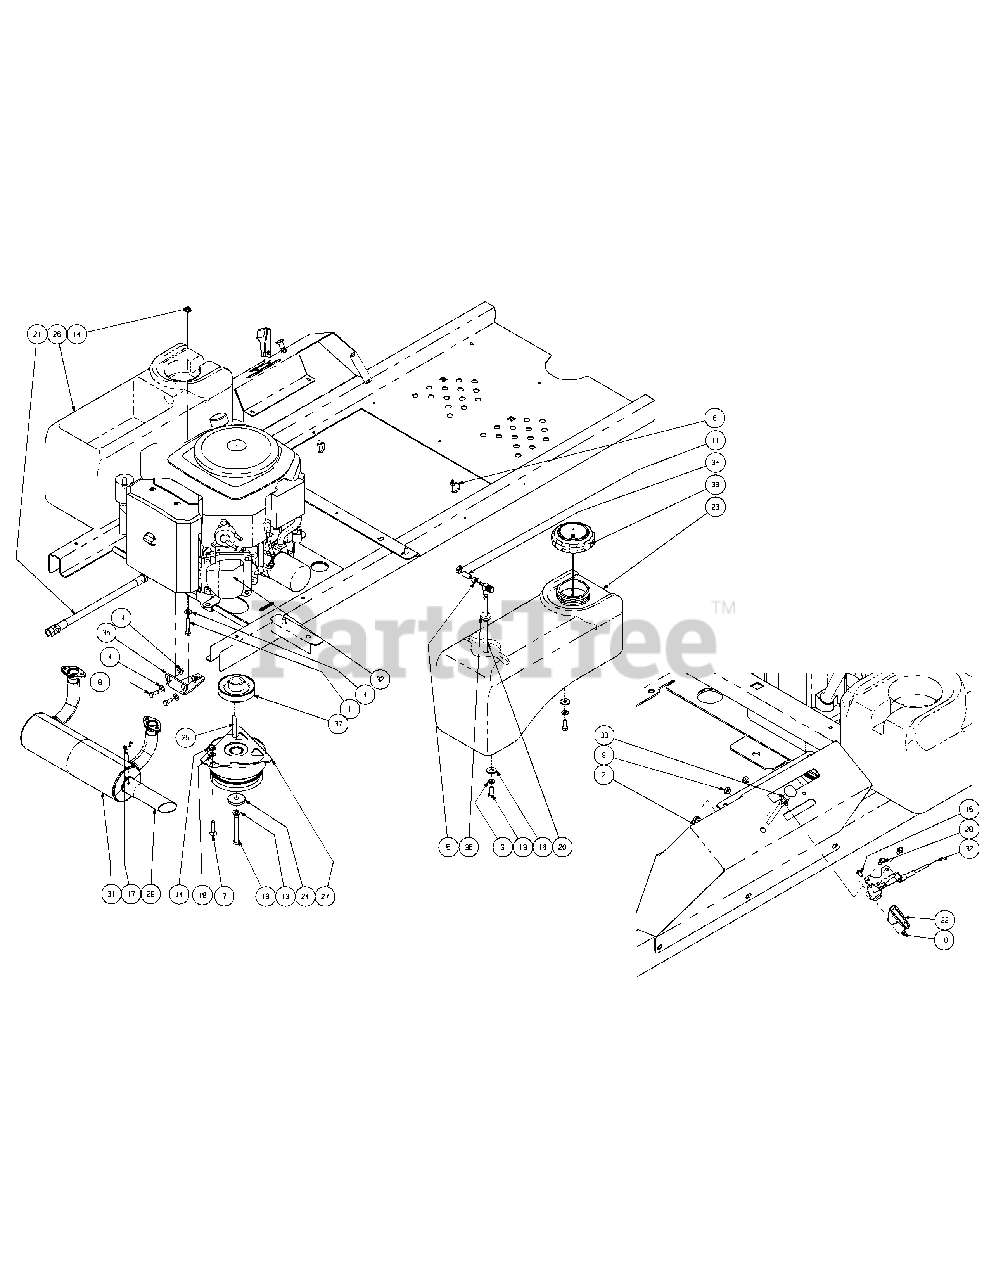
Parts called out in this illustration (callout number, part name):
1	Hex Head Cap Screw, 5/16-18 x 1-3/4
2	Hex Jam Nut, 3/8-24
3	Lock Washer, 3/8 Zinc
4	Flat Washer, 5/16
5	Clamp, Union
6	Cable Tie, 3/16 x .05 x 7.4
7	Carriage Bolt, 5/16-18 x 1.50
8	Hex Cap Screw, 5/16-18 x .75
9	Lock Nut, Nylon Insert, 10-32
10	Nut, w/ Star Washer
11	Hose Clam, 1/4-5/8, SS
12	Hex Cap Screw, 3/8-16 x .88
13	Lock Washer, 7/16
14	Lock Nut, Hex Flange, 5/16-18
15	Machine Screw, 8-32 x .375
16	Flat Washer, .390 ID x 1.0 OD x .180
17	Screw, 8-32 x .375, Hex Washer
18	Hex Cap Screw, 7/16-20 x 3.0
19	Washer, 3/8 x .738 x .063
20	Fuel Pickup Fitting
21	Oil Drain Extension Hose
22	Throttle Control Knob
23	Fuel Tank
24	Flat Washer, 7/16 ID x 1.75 OD x .250
25	Key, 1/4 x 1/4 x 2.75
26	Utility Bin
27	Ogura DX11 Electric Clutch
28	Screw, #10-32 x 0.500
29	Exhaust Pipe
30	20HP Kohler Engine
31	Kohler Muffler
32	Throttle Control Cable
33	Choke Cable
34	Hose, 1/4" Fuel Line
35	Clutch Retainer Assembly
36	Fuel Tank Groment
37	Transmission Drive Pulley
38	Fuel Cap
